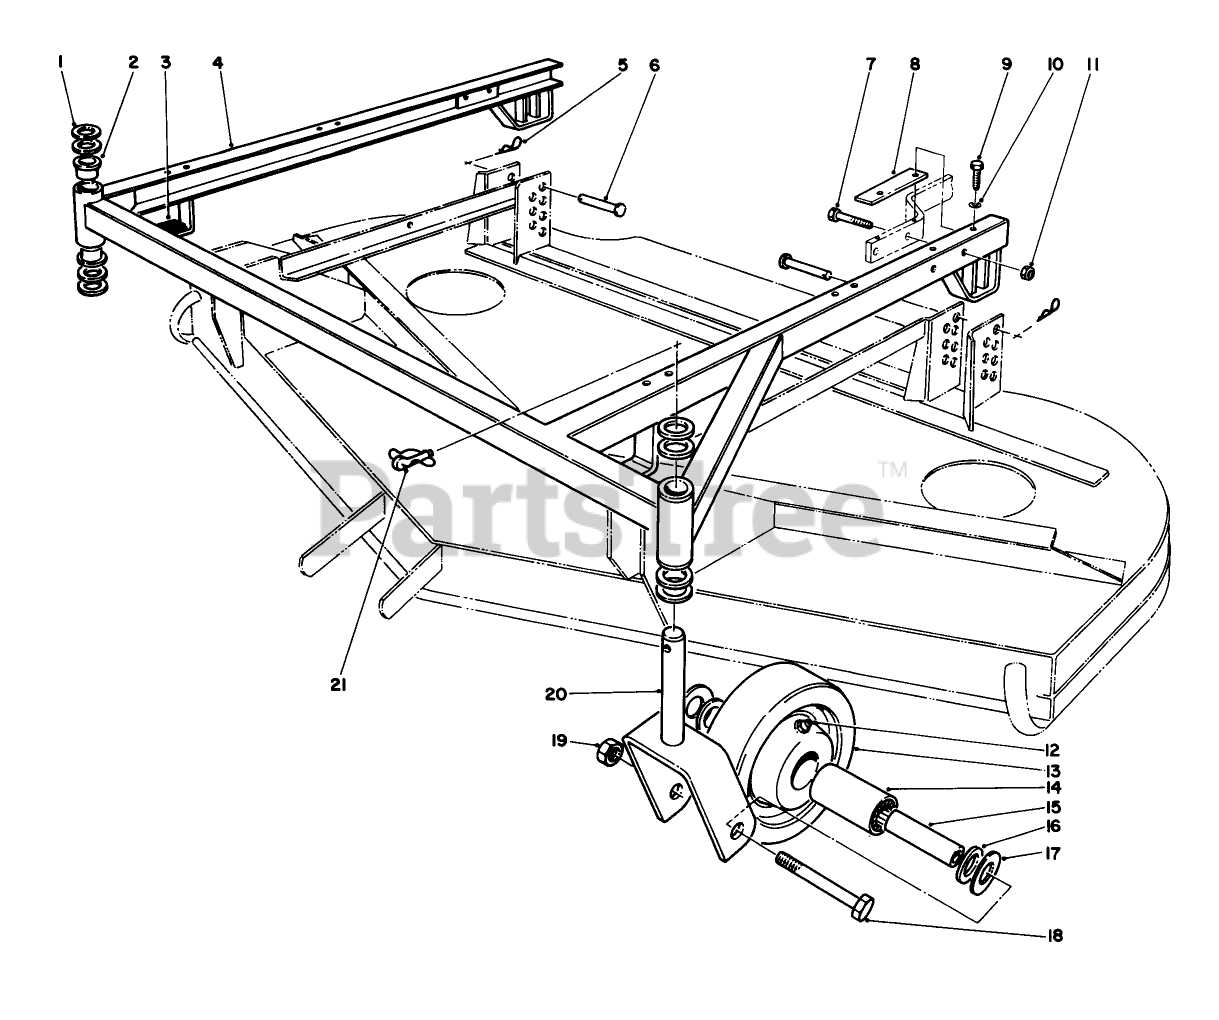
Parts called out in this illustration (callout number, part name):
1	WASHER-THRUST
5	PIN-HAIR
6	PIN-CLEVIS
7	SCREW-HH
8	SHIM-CARRIER
9	SCREW W/PATCH
10	WASHER-FLAT
11	NUT-LOCK, CONE
12	FITTING-GREASE
13	WHEEL
14	ROLLER BEARING
15	SPANNER BUSHING
16	BEARING RETAINER
17	THRUST WASHER
18	SCREW-HH
19	NUT-HEX
21	PIN-LYNCH
